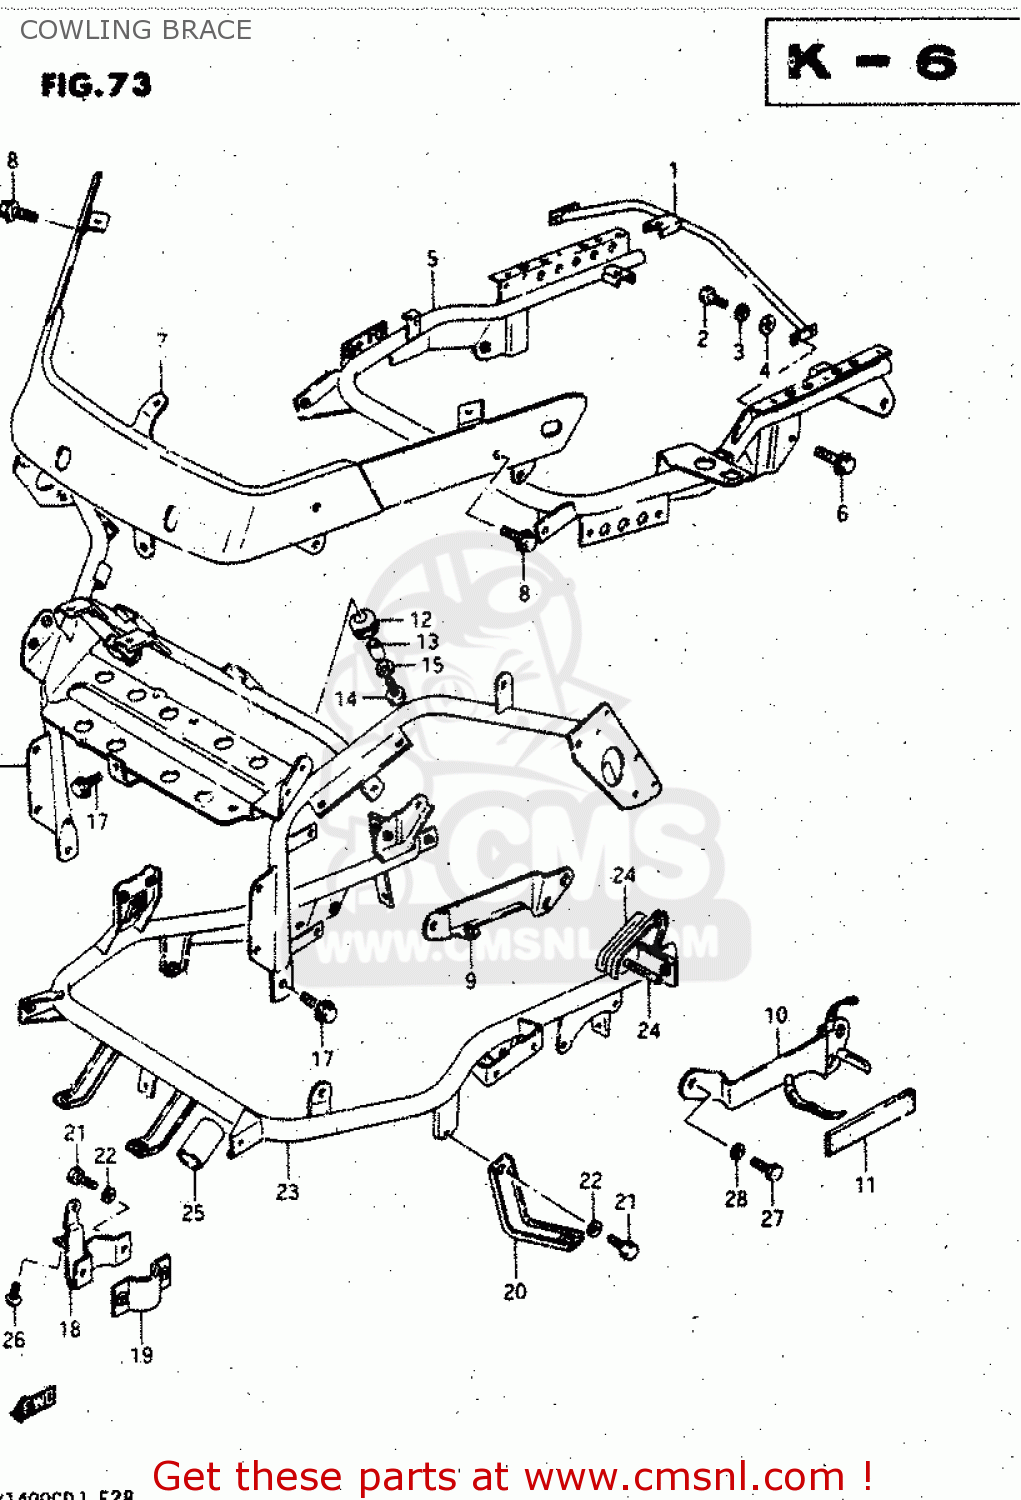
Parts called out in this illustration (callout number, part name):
1	BRACE,CENTER COVER
2	BOLT
3	LOCK WASHER
4	WASHER,5.5X12X
5	BRACE,UPPER
6	BOLT
7	BRACE,SCREEN
8	BOLT
9	REINFORCEMENT,RIGHT
10	REINFORCEMENT,LEFT
11	CUSHION
12	CUSHION
13	SPACER (6.1X8X9.5)
14	BOLT 6X16
15	WASHER (6.5X22X1.6)
16	BRACE,HEADLAMP
17	BOLT
18	BRACKET COMP,COWLING SIDE
19	BRACKET COMP,COWLING SIDE
20	BRACKET COMP,COWLING COVER
21	BOLT
22	WASHER,LOCK
23	BRACE COMP,REAR
24	MOLDING,FUEL TANK
25	PROTECTOR,REAR BRACE
26	SCREW
27	BOLT 6X16
28	WASHER (6.5X22X1.6)
